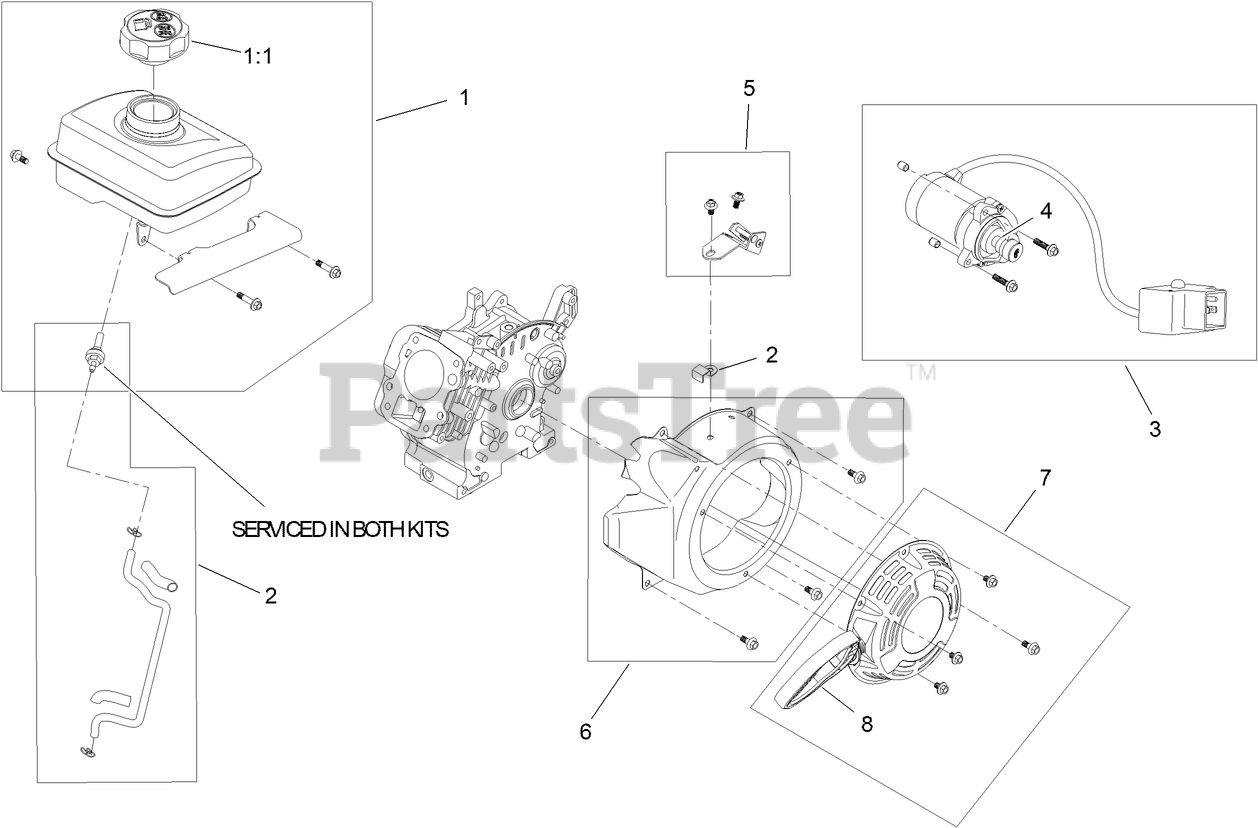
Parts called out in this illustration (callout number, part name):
1	FUEL TANK AND CAP KIT
1:1	CAP-FUEL
2	FUEL LINE KIT
3	ELECTRIC STARTER KIT
4	PINION KIT
5	GOVERNOR KIT
6	BLOWER SHROUD KIT
7	RECOIL ASM KIT
8	HANDLE-RECOIL
